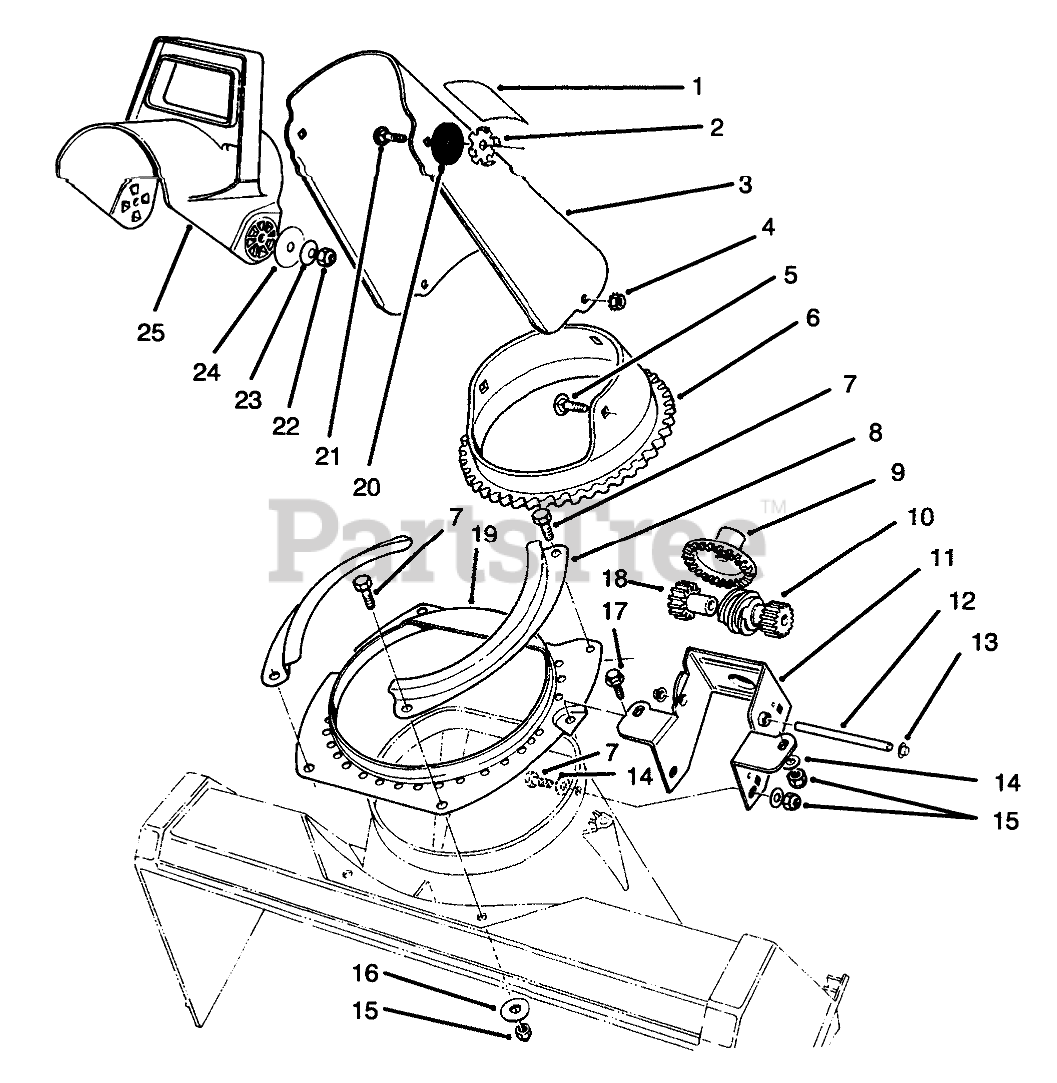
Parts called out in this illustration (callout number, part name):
1	DECAL - DANGER DISCHARGE
2	PLATE-FRICTION
3	Chute-Discharge (Model No. 38185) (Incl. Ref. #1)
4	NUT-KEPS
5	SCREW-CARR
6	RING-GEAR, CHUTE
7	SCREW-HH
8	Retainer-Chute Ring
9	GEAR-FACE
10	GEAR-SPUR/WORM
11	Bracket-Chute Gear
12	SHAFT-GEAR, WORM
13	NUT-PUSH
14	WASHER-FLAT
15	NUT-LOCK, NI
16	WASHER-FLAT
17	SCREW-PLASTITE
18	GEAR-SPUR, SPACER
19	Ring-Chute Support
20	WASHER-RUBBER
21	SCREW-CARR
22	NUT-LOCK, NI
23	WASHER-BELLEVILLE
24	WASHER-FLAT
25	CHUTE-DEFLECTOR
